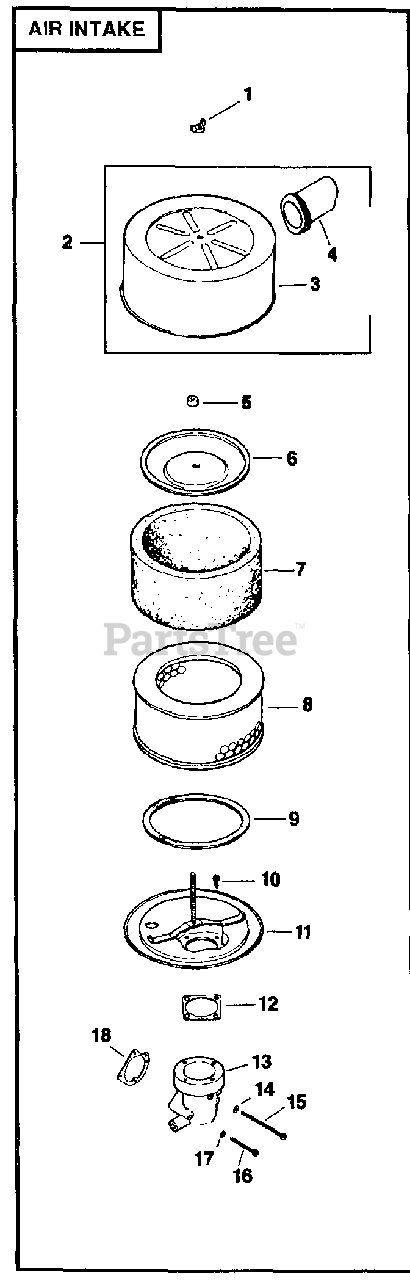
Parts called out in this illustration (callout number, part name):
1	WING NUT
3	COVER AIR CLEANER
4	TUBE AIR INTAKE
5	SEAL ELEMENT
6	COVER AIR CLEANER ELEMENT
9	SEAL
10	SCREW
12	GASKET
13	ELBOW AIR INTAKE
14	WASHER
15	SCREW
16	SCREW
17	WASHER
18	GASKET, AIR CLEANER
